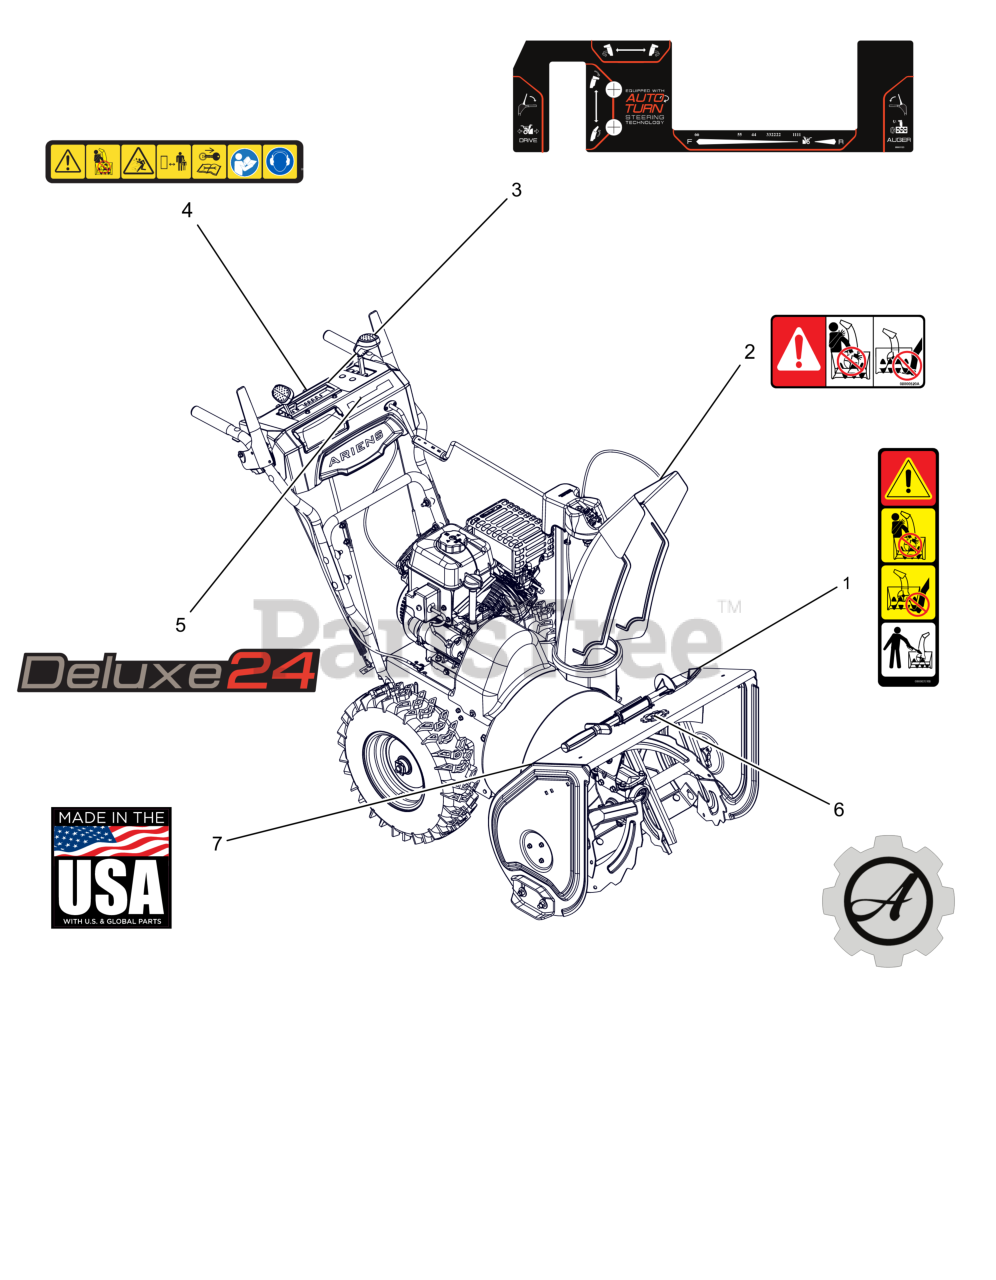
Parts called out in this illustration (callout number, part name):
1	DECAL, DANGER - ROTATING PARTS
2	DECAL, DANGER
3	DECAL,CONTROL-SML,AT,ID
4	DECAL,DASH - SAFETY
5	DECAL, DASH - DELUXE 24
6	DECAL, ARIENS-GEAR BADGE -THK
7	DECAL, MADE IN USA
